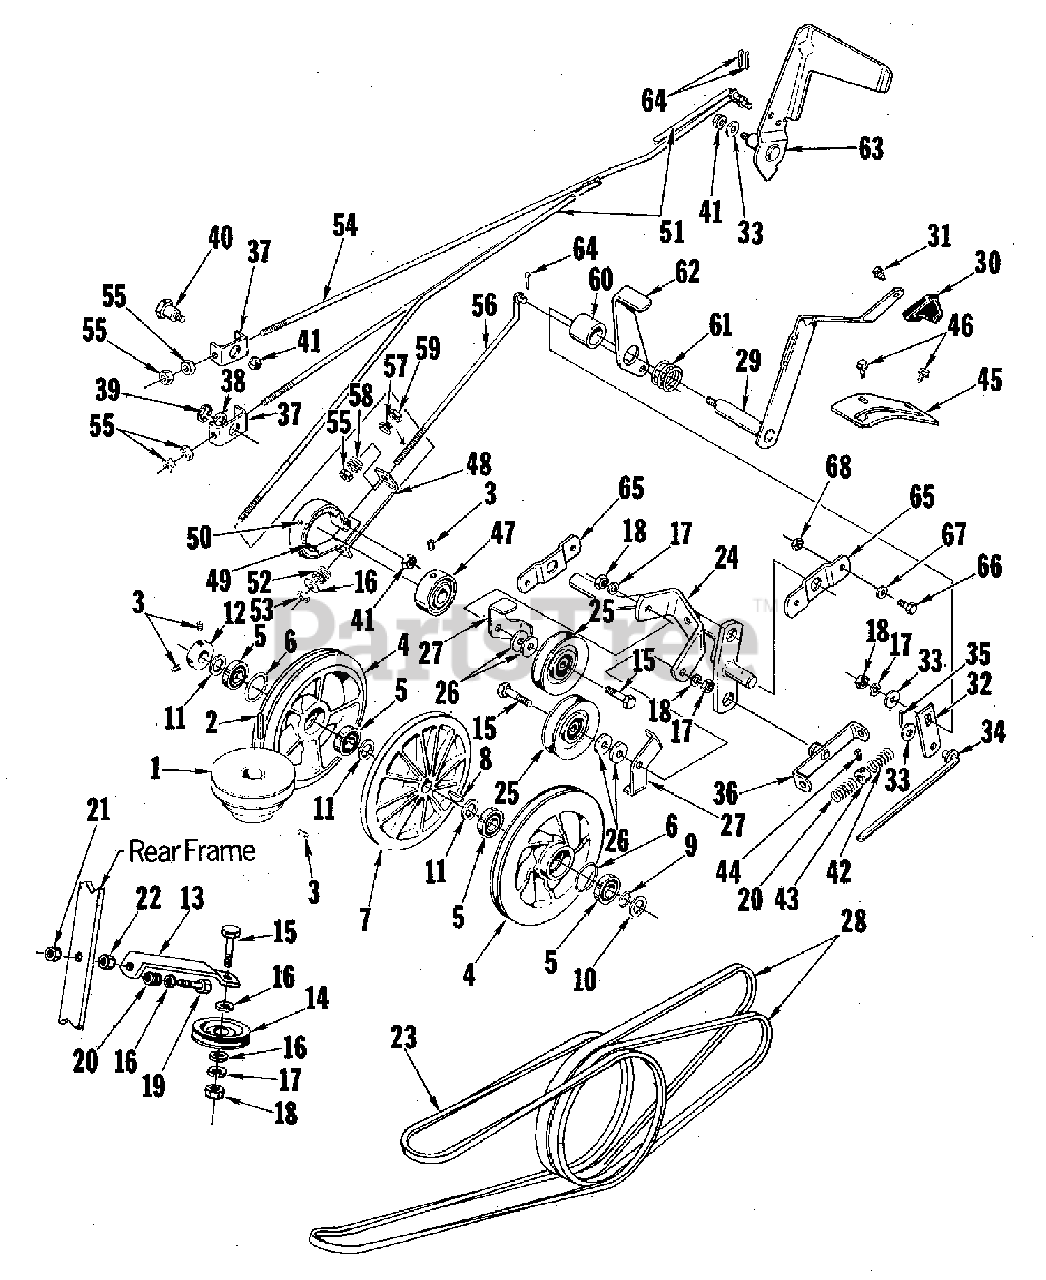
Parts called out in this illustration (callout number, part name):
1	PULLEY, Engine
3	SCREW, Set, 5/16-18 x 5/16
4	PULLEY, Outer
6	RING, Retaining
7	CLUTCH, Center Disc
9	RING, Retaining
13	BRACKET, Idler
14	PULLEY, Idler
15	SCREW, Hex, 3/8-16 x 1-1/2
16	WASHER, Plain, 5/16
17	WASHER, Lock, 3/8
18	NUT Hex, Full, 3/8
19	SCREW, Hex, 3/8-16 x 4
21	NUT, Hex Lock, 3/8-16
22	NUT, Hex, 3/8-16
24	BRACKET, Pivot
25	PULLEY, Idler
26	WASHER, Special
29	LEVER, Control
31	SCREW, Thread Forming, 1/4-20 x 7/8
33	WASHER, Plain, 3/8
35	PIN, Cotter, 1/8 x 1
39	RING, Retaining
40	BOLT, Shoulder
41	NUT, Flange Lock, 3/8-26
44	SCREW, Set, 1/4-20 x 3/8
46	SCREW, Swageform, 5/16-18 x 1/2
48	BRAKE BAND ASSEMBLY
49	BRAKE, Lining
53	NUT, Hex Full Lock, 5/16-18
55	NUT, Hex Full, 3/8-16
56	ROD, Parking Brake
59	NUT, 5/16-18
63	PEDAL, Brake
64	PIN, Cotter, 3/32 x 3/4
65	PIVOT, Support
66	SCREW, Hex, 3/4-20 x 3/4
67	WASHER, Plain, 1/4
68	NUT, Flange, 1/4-24
